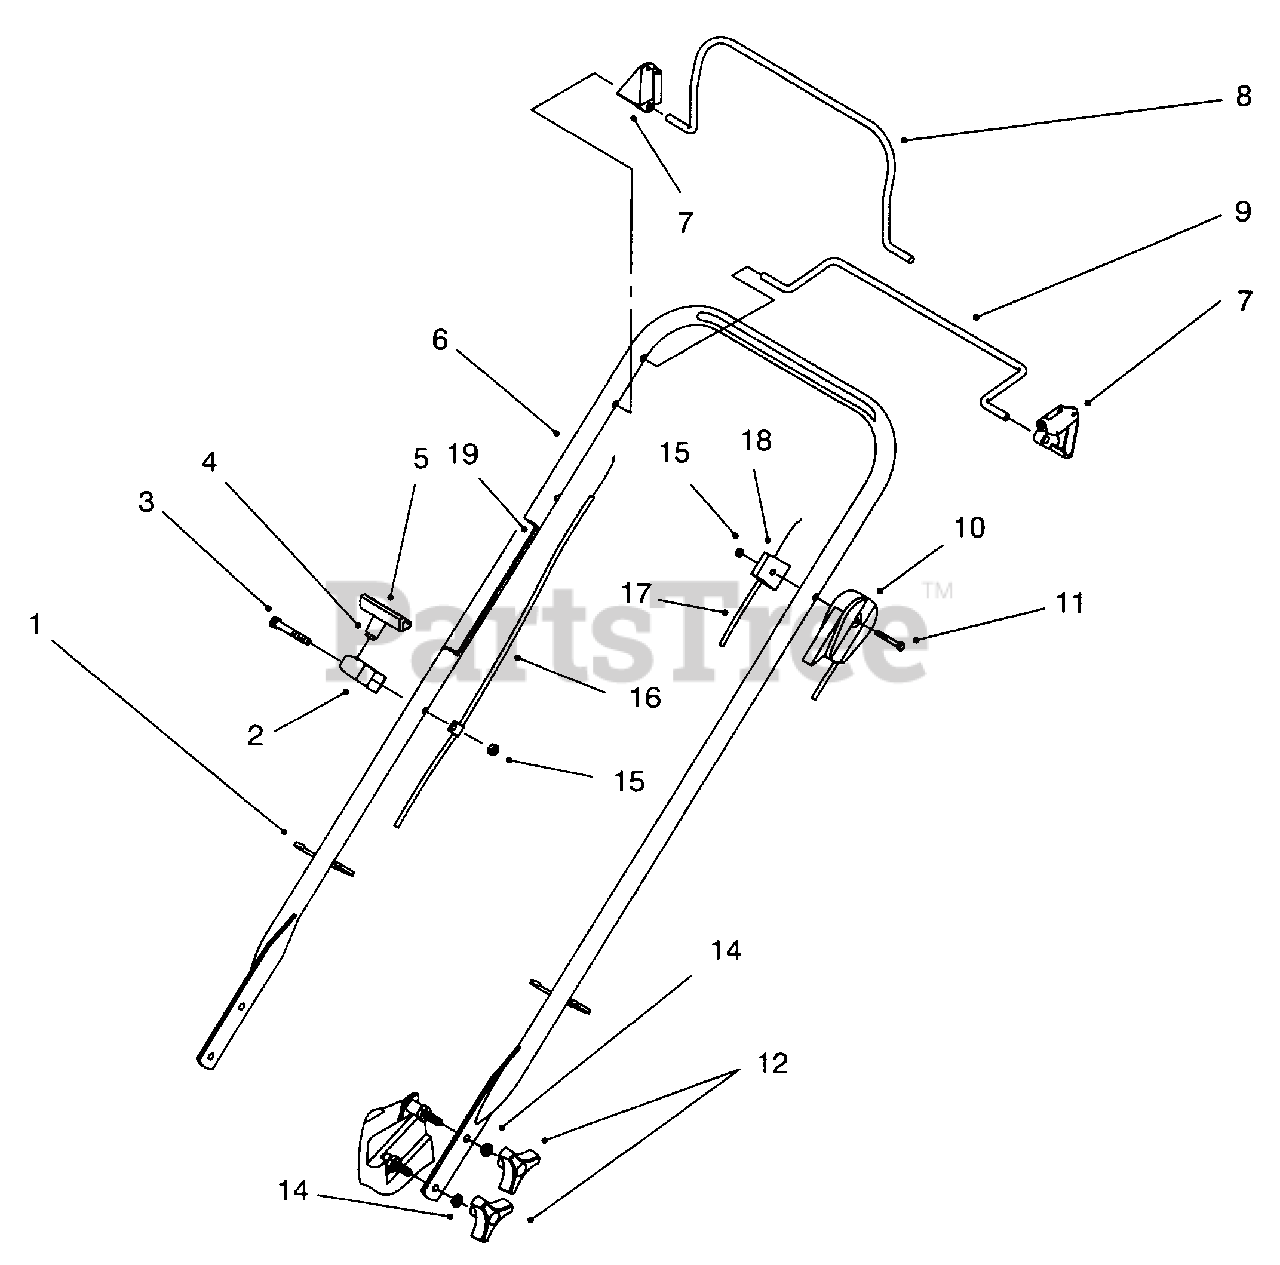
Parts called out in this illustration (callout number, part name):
1	Tie Cable
2	Guide-Rope
3	Screw-Hex Hd. Cap
4	Handle-Starter
5	Clip-Rope Insert
7	Stop-Pivot
8	Bail-Flywheel Brake
9	Bail-S.P. Control
10	Cable-Throttle
11	Screw-Hex Hd. Cap
12	Knob
14	Washer-Lock
15	Nut-Lock Insert
16	Cable-Brake
17	Cable-Traction
18	Anchor-Cable S.P. Upper
19	Decal-Operation
